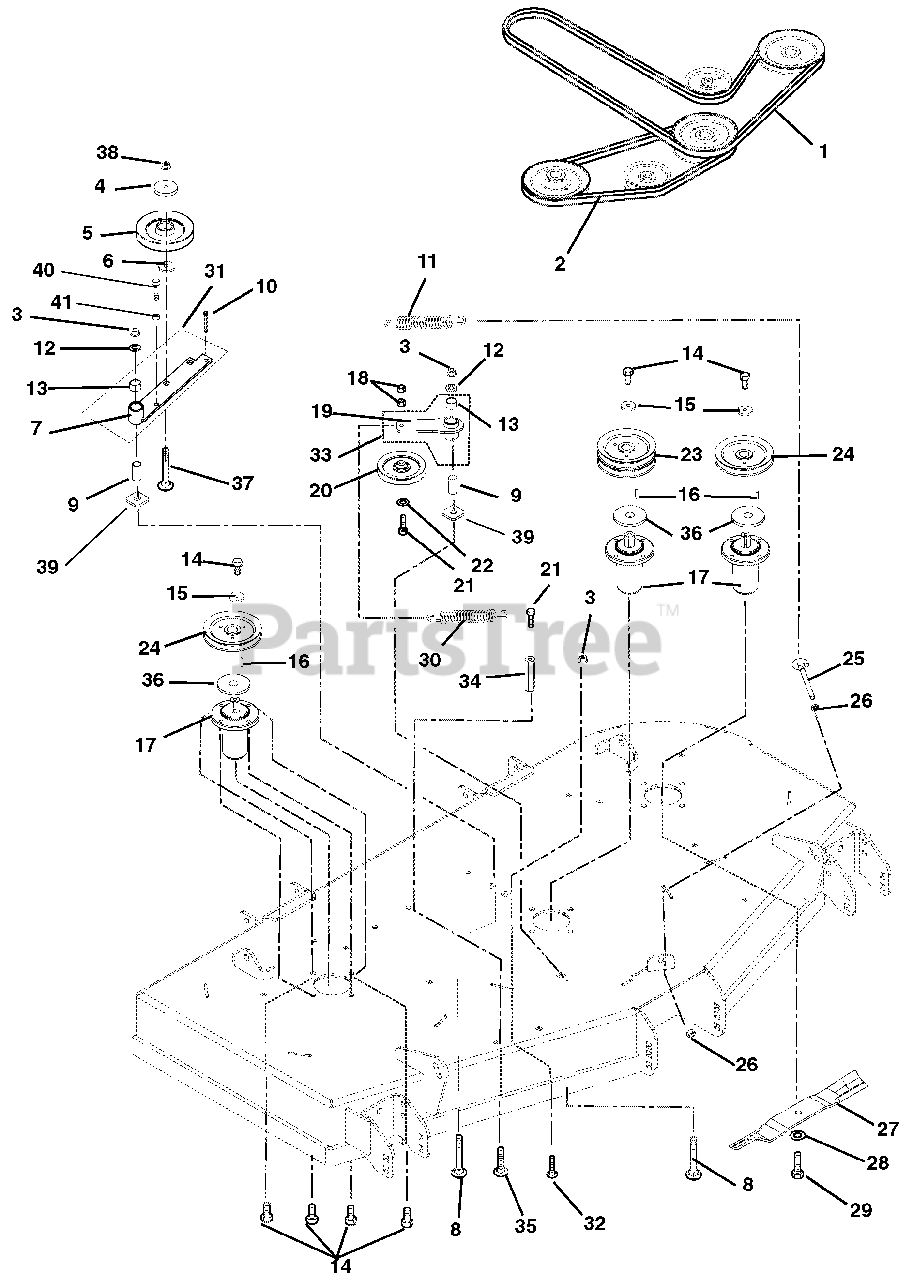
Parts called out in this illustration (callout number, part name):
1	Belt, 175" Long, PTO Drive Hex (992322)
2	V-Belt, 56" Long Cog B-Section (992322)
3	Nut, .50-13 Nyloc Flange
4	Cap, Idler Bearing Sealing
5	Pulley, V 6.0 x .500 ID SNGL. Bearing
6	Bushing, Spacer .502 x .997 x .50
7	Weldment, Idler Arm
8	Bolt, Round Head Square Neck .50-13 x 3.50
9	Bushing, Spacer .505/.500 x .999/.996 x 2.05/2.03
10	Bolt, Shoulder EP .38-16 x .30 Hex
11	Spring, Extension (Deck Idler)
12	Washer, Flat Steel .531x 1.250 x.100
13	Bushing, 1.00 x 1.125 x 1.936
14	Bolt, Hex .38-16 x 1.00
15	Washer, Flat Steel .406 x 1.50 x .245
16	Key, Square .25 x .25 x 1 RC 40-50
17	Spindle Assembly
18	Nut, Locking Center .38-16
19	Weldment, Idler Arm
20	Assembly, V-Idler 5.00 O.D.
21	Bolt, Hex .38-16 x 2.25
22	Washer, Flat Steel .406 x .812 x .065
23	Sheave, Double 1" ID x 6.00" OD (992322)
24	Sheave, Single 1" ID x 6.00" OD (992322)
25	Bolt, .38-16 x 4.50 .62 Diameter Eye
26	Nut, Hex, Jam .375-16
27	Blade, 18.00" Mower, Mulch (992322)
28	Washer, Bellville .63 x 1.625 x.14
29	Bolt, Hex .62-18 x 1.75 Grade 8
30	Spring, Extension
31	Assembly, PTO Idler Pivot Arm (Includes item # 7 and item # 13)
32	Bolt, Round Head Square Neck .50-13 x 1.5, Full Thread, Grade 5
33	Assembly, Idler Pivot Arm (Includes item # 13 and item # 19 )
34	Nut, Coupling .375-16 x 1.75
35	Bolt, Round Head Square Neck .38-16 x 1.00
36	Retainer, Grease
37	Bolt, Round Head Square Neck .50-13 x 3.00 Grade 5
38	Nut, Locking Center .50-13
39	Washer, Flat .640 x 1.75 x .250
40	Bolt, Hex .38-16 x 2.75
41	Nut, Hex .38-16
